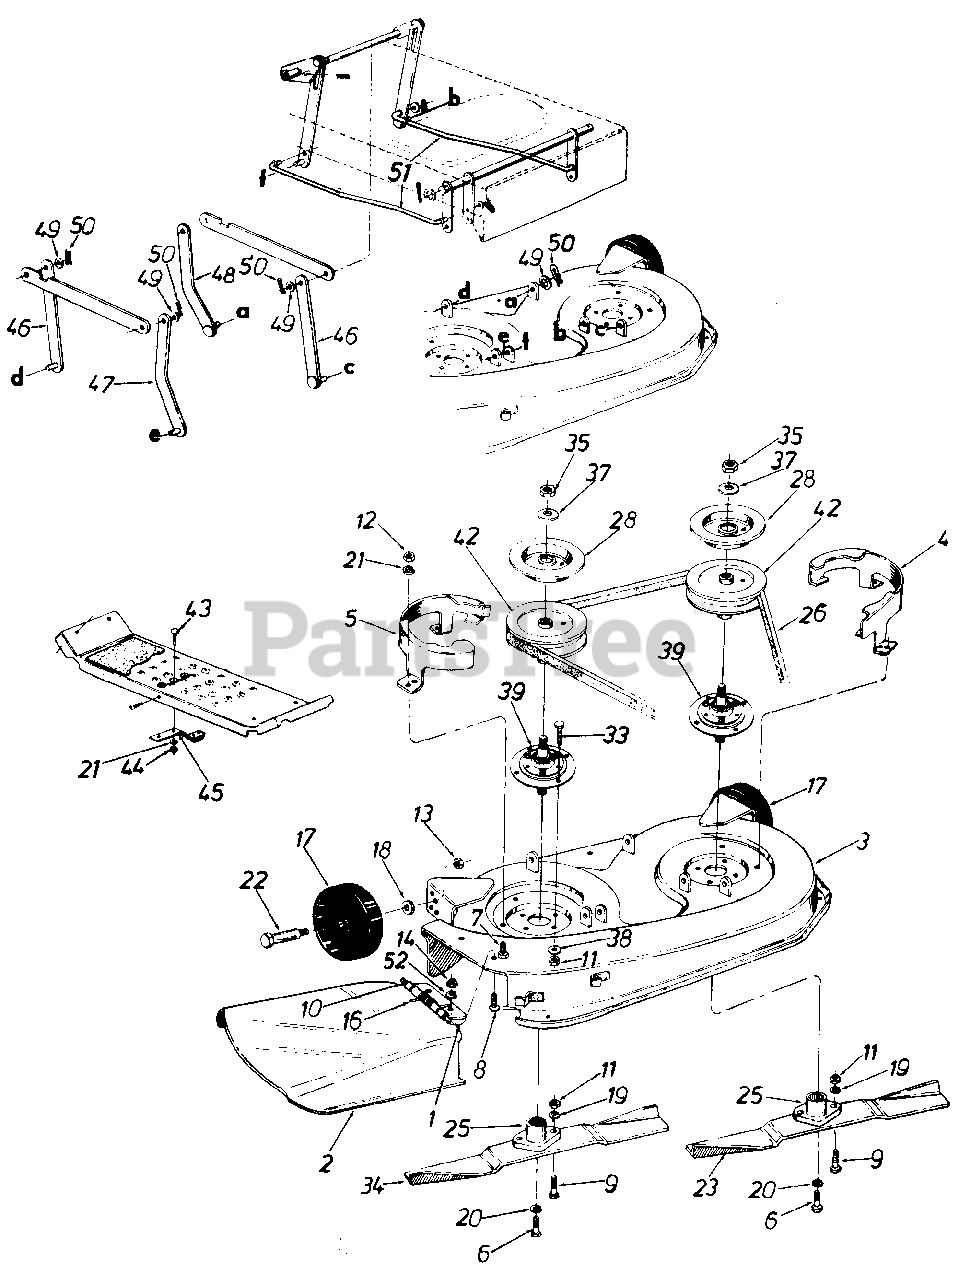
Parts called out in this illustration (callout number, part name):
1	Chute Bracket
2	Chute Deflector
3	38" Deep Deck Ass'y.
6	Hex Bolt 3/8-24 x 1.00"
7	Hex Bolt 1/4-28 x .62"
8	Truss Mach. Scr. 1/4-20 x .75"
9	Hex Bolt Special 5/16-24 x 1.O"
10	Hinge Pin
11	Hex Nut 5/16-24 Thd.
12	Hex Nut 1/4-28 Thd.
13	Hex Top L-Nut 3/8-16 Thd.
14	Hex Jam Nut 1/4-20 Thd.
16	Torsion Spring
17	Deck Wheel 5"
18	Bell-Wash. .40" I.D. x .88" O.D.
19	L-Wash. 5/16" I.D.
20	L-Wash. 3/8" I.D. H.D.
21	L-Wash. 1/4" I.D.
22	Shld. Bolt .498" Dia. x 1.53"
23	High-Lift Blade L.H.
25	Blade Adapter
26	5L V-Belt
28	Brake Disc
33	Rib Neck Bolt 5/16-24 x 1.05" Lg.
34	High-Lift Blade R H
35	Hex Jam Nut 5/8-18 Thd.
37	L-Wash. 5/8" I.D.
38	L-Wash. 5/16" I.D.
39	Blade Spindle Ass'y. Comp.
42	5" Dia. Pulley
43	Carr. Bolt 1/4-20 x .62"
44	Hex Nut 1/4-20 Thd.
45	Blade Brake Ass'y.
46	Link Deck Hanger Ass'y.
47	Link Deck Hanger Ass'y.
50	Inter. Cotter Pin .50" Dia.
51	Stabilizer Rod
52	Bell-Wash. 1/4" I.D.
